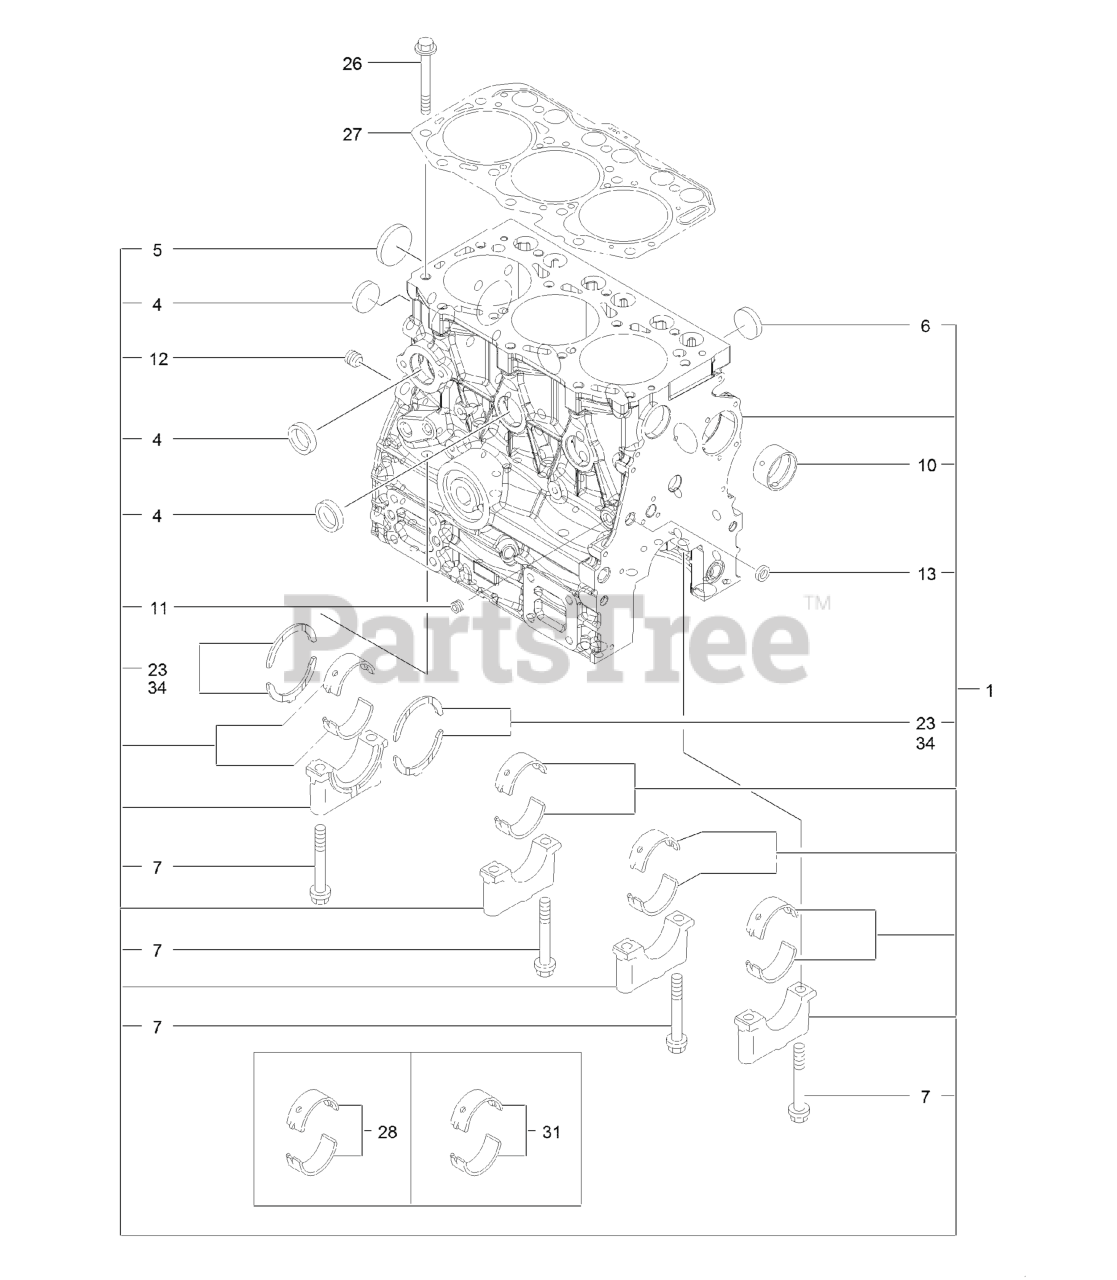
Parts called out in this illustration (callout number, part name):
1	BLOCK ASM-CYLINDER
4	PLUG, CUP TYPE 30
5	PLUG-DISH
6	PLUG-CUP TYPE 25
7	BOLT-METAL CAP
10	BUSH-CAMSHAFT
23	BEARING ASSY-THRUST
26	BOLT, CYLINDER HEAD
27	GASKET SET-HEAD
28	BEARING ASSY-MAIN
31	BEARING ASSY-MAIN
34	BEARING-THRUST
